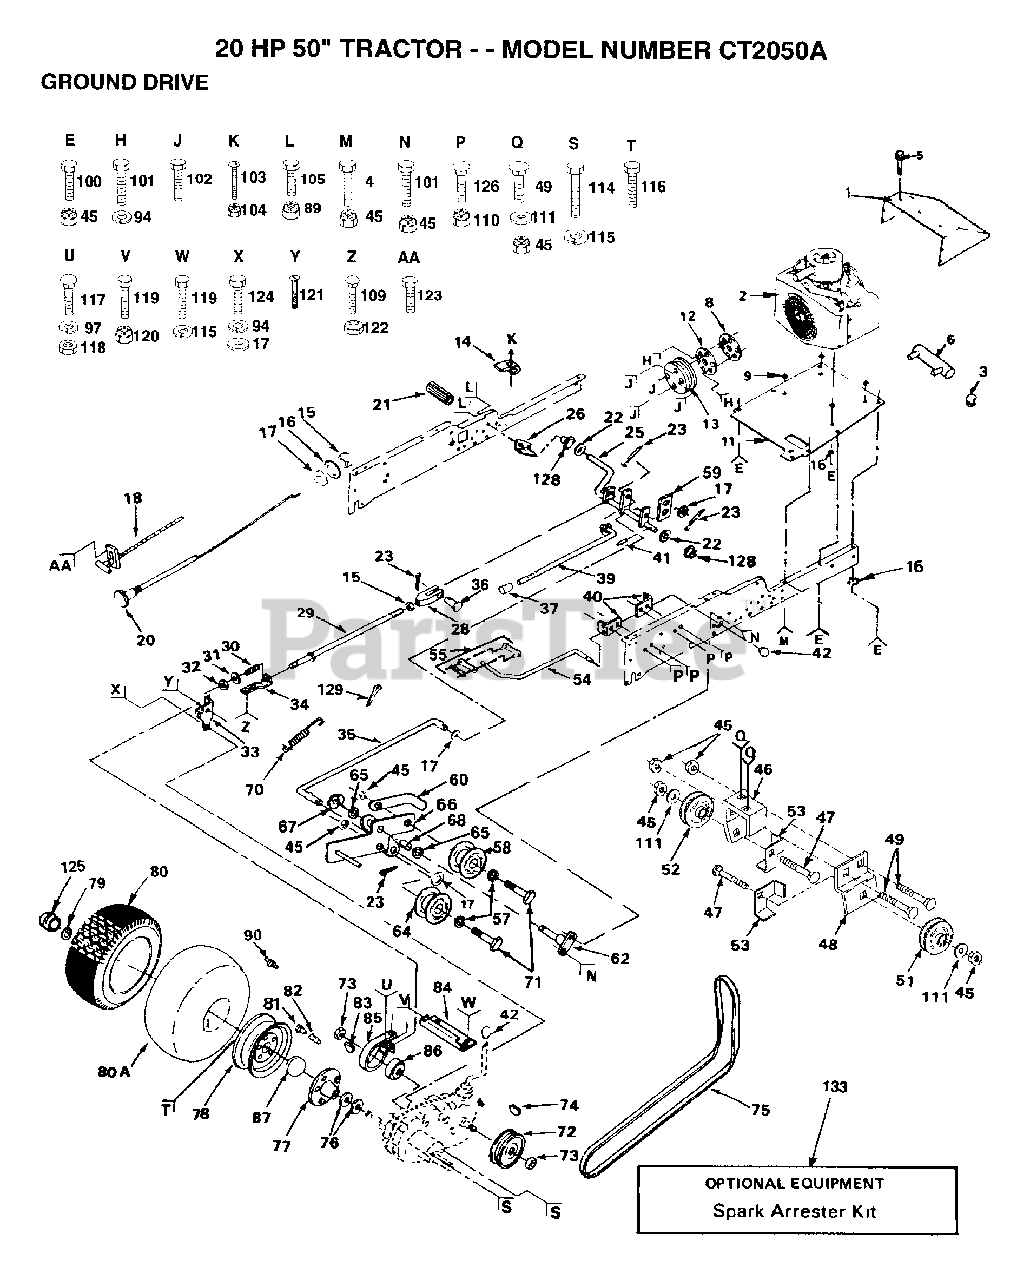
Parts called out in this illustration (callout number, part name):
1	NUT IGNITION
3	PIPE, EXHAUST
4	"BOLT,HEX"
5	SCREW
8	CHAFF GUARD T
9	SPACER.ENGINE KOH
11	"ENG. T, BASE"
12	ADAPTER T
14	ACT-SWITCH T
16	LOCKWASHER
17	WASHER
21	PEDAL COVER T
22	WASHER
25	SHAFT ASSY GT
26	BRKT SWITCH GT
28	YOKE GTV
29	BRAKE ROD T
30	SPRING T
31	WASHER
33	BRAKE BRKT ASSY T
34	GUIDE ROD T
35	ROD CLUTCH GTV
36	CLEVIS PIN T
40	ROD BRACKET GT
41	ROLL PIN STD
42	CONTROL KNOB LT
47	BOLT
48	BRKT IDLER FLAT
49	BOLT
51	IDLER-FLAT T
52	PULLEY V IDLR GTV
53	GUARD BELT
55	ROD SHIFT HI LO
57	WASHER
59	RETAINER SPRING
60	RETAINER BELT
62	BRACKET ASSY GTV
65	WASHER T
66	BRACKET CLUTCH
67	KLIP RING
68	"LY, BEARING"
69	BRAKE ROD
70	SPRING EXT CLUTCH
73	NUT STD
75	BELT-V.98.5.GD.DV
76	WASHER T
79	KLIP RING
80A	TUBE.23X8/10-12
81	VALVE CAP
82	VALVE STEM LT
85	BRAKE BAND ASM
86	BRAKE DRUM T
87	"COVER, HUB"
90	ZERK FITTING M
94	LOCKWASHER
97	LOCKWASHER
101	BOLT
102	SCREW
103	SCREW
105	BOLT LT
111	WASHER GT
114	BOLT
115	LOCKWASHER
117	BOLT T
119	BOLT
120	NUT GTV
121	SCREW
123	SCREW LT
125	CAP-HUB GT
126	BOLT
128	NYLINER T
129	COTTER PIN
133	SPARK ARREST KIT
